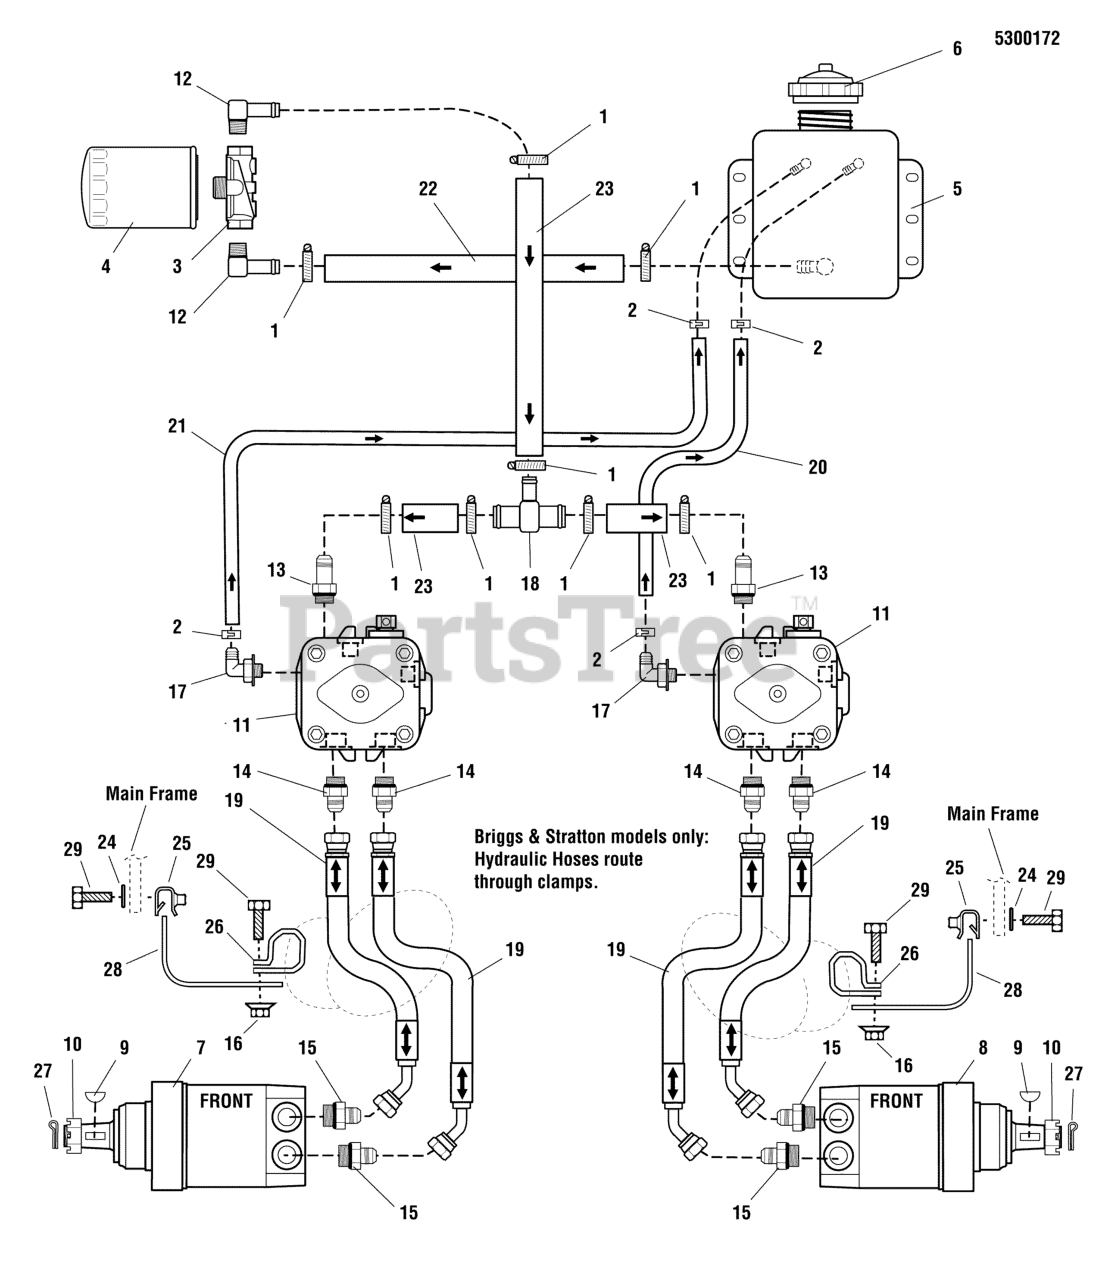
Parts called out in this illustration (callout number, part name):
1	CLAMP, #10 HOSE STAINLESS
2	CLAMP, HOSE
3	FILTER HEAD
4	FILTER, HYDRAULIC, SERVICE PART (PKG)
5	KIT, TANK HYDRAULIC, 3QT W/ FITTINGS
6	CAP, HYDRAULIC RESERVOIR
7	* MOTOR, WHEEL REAR PORT LH 15CI
8	* MOTOR, WHEEL REAR PORT RH 15CI
9	KEY
10	CASTLE NUT
11	HYDRAULIC PUMP W/ FAN BRACKET AND LEVER
11	7" FAN HUB ASSEMBLY
11	KIT, OVERHAUL SEAL
11	SEAL, OUTPUT SHAFT, 17 X 40 X 7
12	FITTING, 1/2NPT-5/8" HOSE, 90 DEG
13	FITTING, STRAIGHT, HYD #12618
14	ADAPTER, HYDRAULIC
15	ADAPTER, HYDRAULIC
16	NUT, 5/16-18 HEX SERRATED FLANGE (SMALL)
17	ADAPTER, 90 DEG, 9/16-3/8 BARB
18	TEE, HYDRAULIC, BEADED HOSE, 5/8 X 5/8 X 5/8
19	HOSE ASSEMBLY, (33)
20	HOSE, 3/8" PUSH-LOCK, 12.00"
21	HOSE, 3/8" PUSH-LOCK, 17.50"
22	HOSE, 5/8" PUSH-LOCK, 11.50"
23	HOSE, 5/8" PUSH-LOCK, 10.00"
24	WASHER, 5/16" SAE
25	BODY CLIP, 5/16-18-7GA MATERIAL
26	CLAMP, VINYL 1.75-1.81
27	COTTER PIN
28	PLATE, HOSE ANCHOR
29	BOLT, 5/16-18 X 1" GD5 YZ
